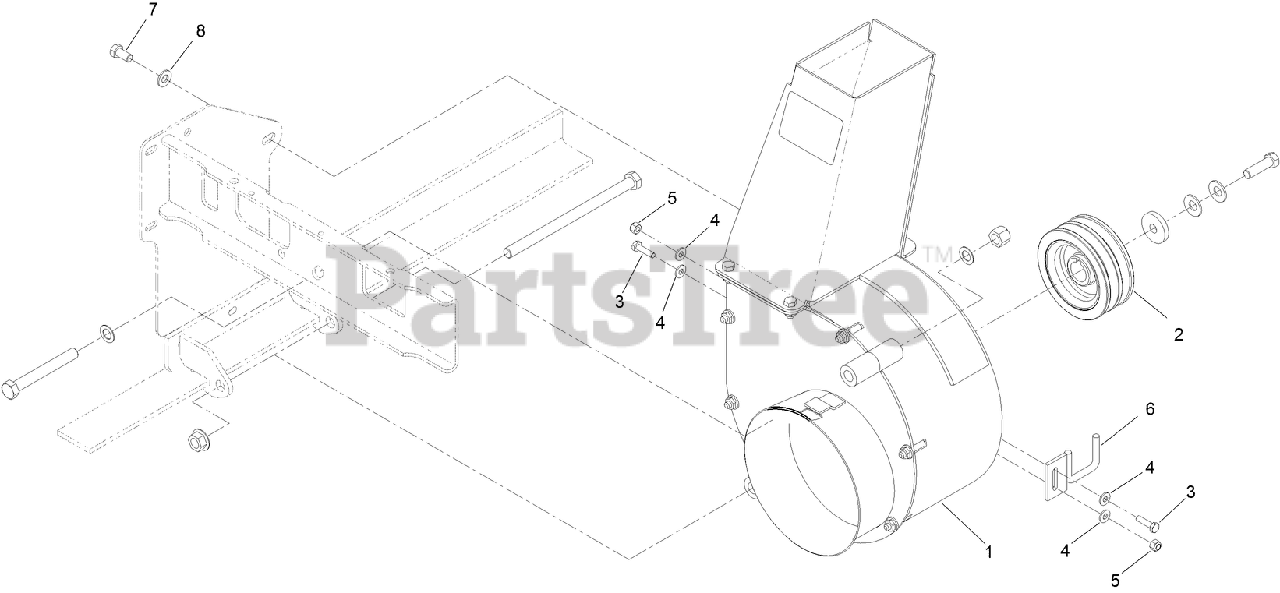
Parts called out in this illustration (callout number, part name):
1	BLOWER ASM
2	Sheave-Blower
3	SCREW-HH
4	WASHER-FLAT
5	NUT-LOCK, NI
7	SCREW-HH
8	WASHER-FLAT
